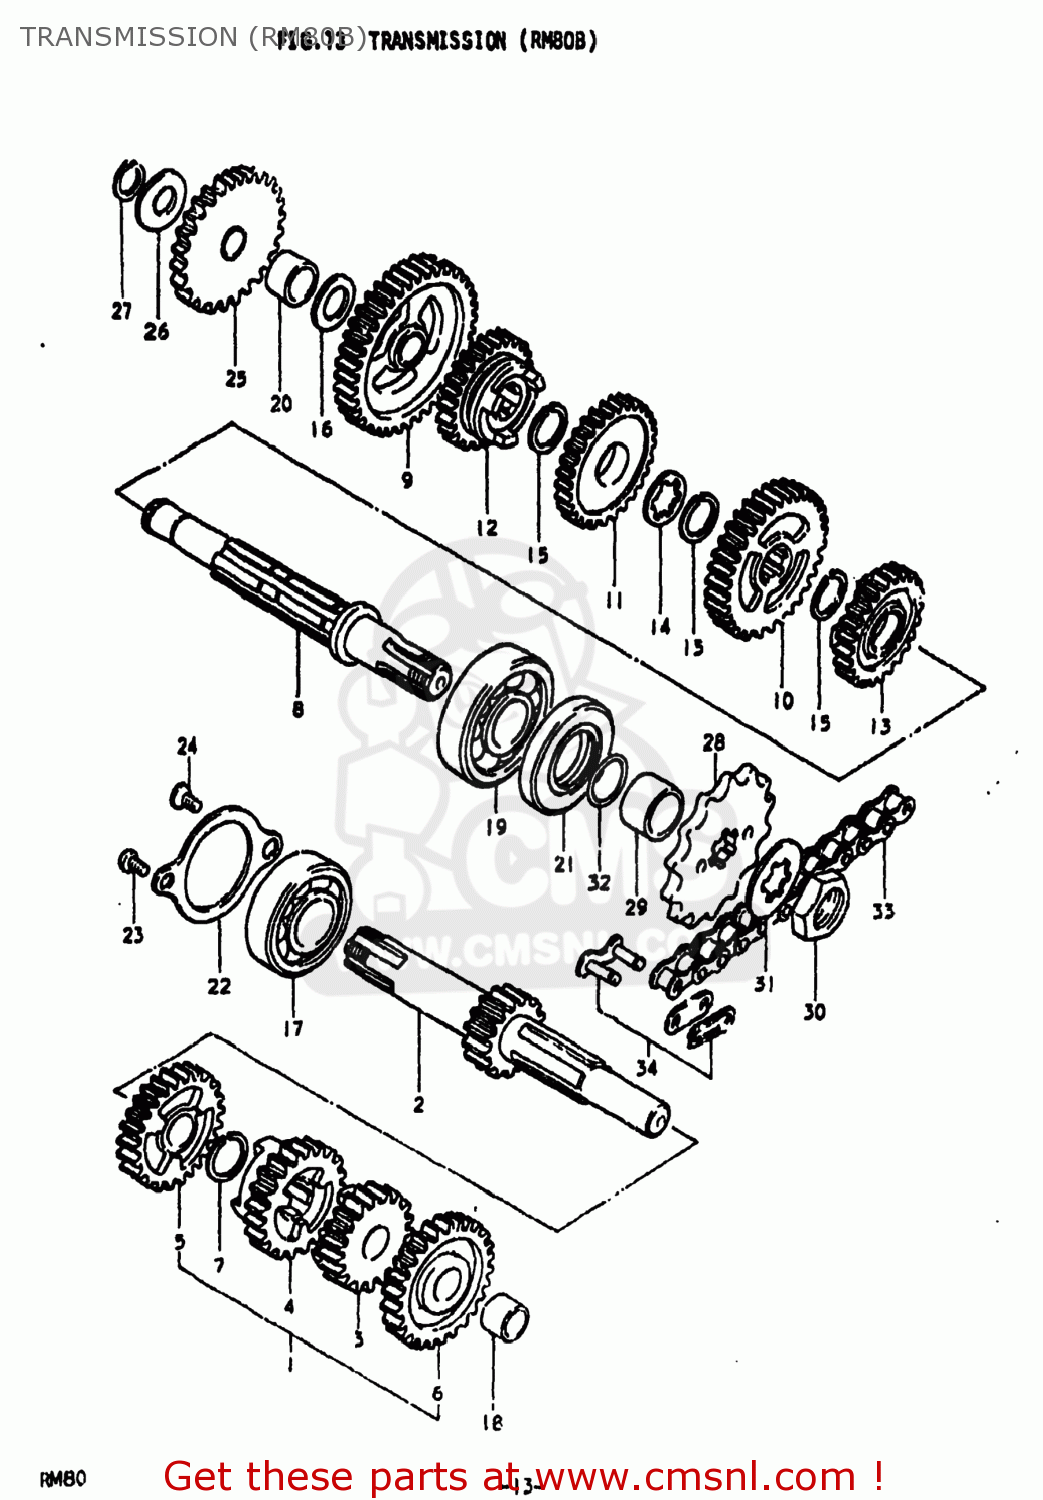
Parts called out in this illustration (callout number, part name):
1	SHAFT,COUNTER
2	SHAFT,COUNTER(NT:12)
3	GEAR,SECOND DRIVE
4	GEAR,THIRD DRIVE
5	GEAR,4TH DRIVE(NT:24)
6	GEAR,FIFTH DRIVE
7	CIRCLIP
8	SHAFT,DRIVE
9	GEAR,FIRST DRIVEN
10	GEAR,2ND DRIVEN(NT:33)
11	GEAR,3RD DRIVEN(NT:29)
12	GEAR,4TH DRIVEN(NT:36)
13	GEAR,5TH DRIVEN(NT:24)
14	WASHER(13X24X1)
15	CIRCLIP
16	WASHER,LOCK
17	BEARING
18	BUSH
19	BEARING
20	BUSH
21	SEAL,OIL(21X40X6)
22	RETAINER,CNTR SHAFT BEARING
23	SCREW
24	SCREW
25	GEAR,KICK STARTER IDLE
26	WASHER
27	CIRCLIP.12MM
28	SPROCKET,ENGINE
29	SPACER(17X21X13)
30	NUT
31	WASHER,LOCK
32	O RING(D:1,ID:16.8)
33	CHAIN ASSEMBLY,DRIVE
34	JOINT ASSEMBLY,CHAIN
